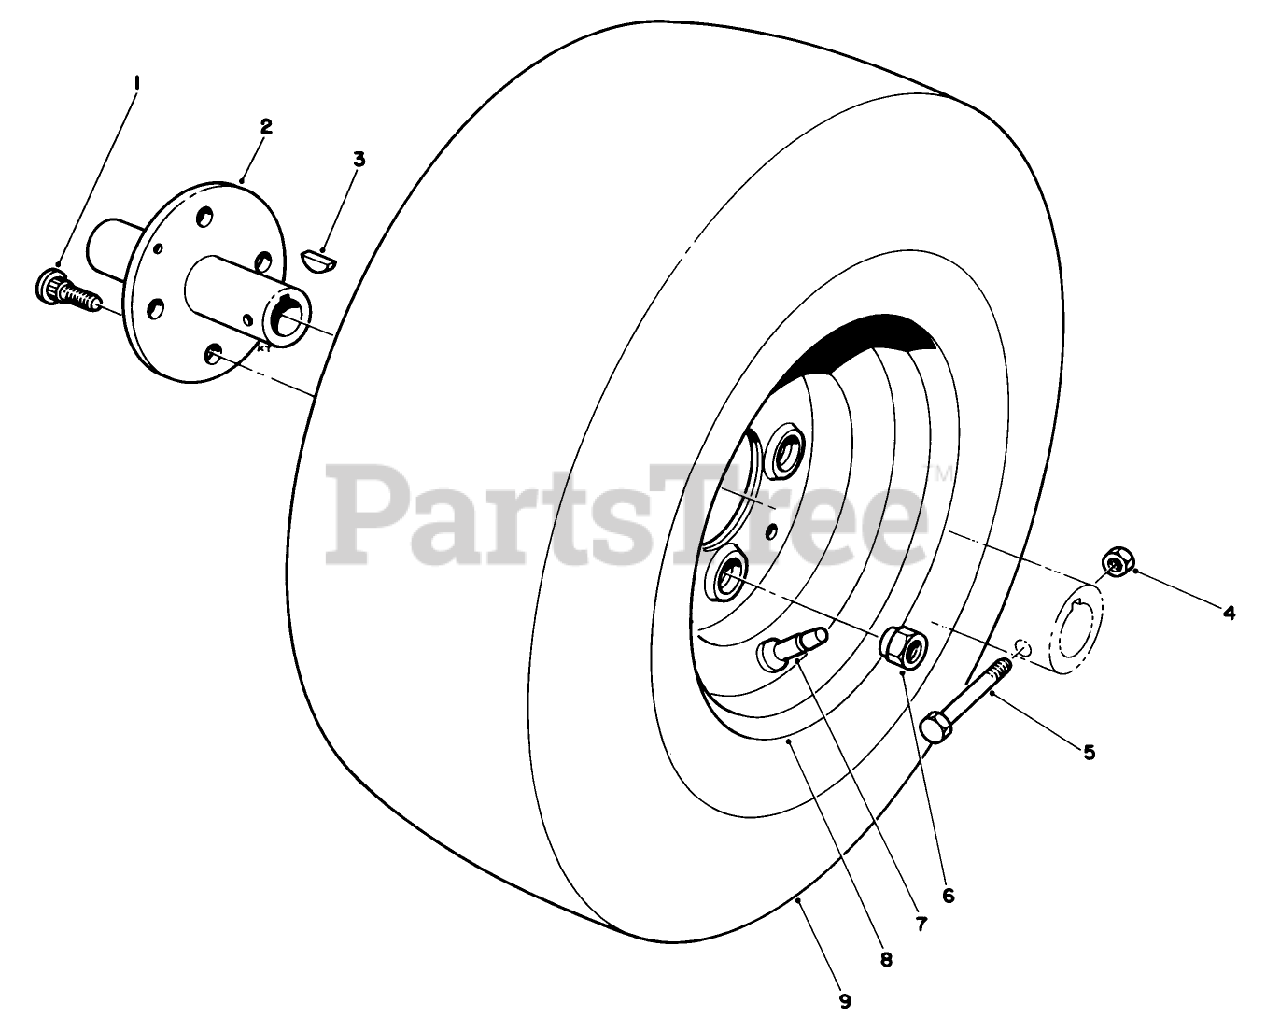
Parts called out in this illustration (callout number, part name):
1	1/2-20X1.25 BOLT
2	WHEEL HUB
3	KEY-WOODRUFF
4	NUT-LOCK, NI
5	SCREW-HH
6	NUT-LUG
7	STEM-VALVE
9	Tire
